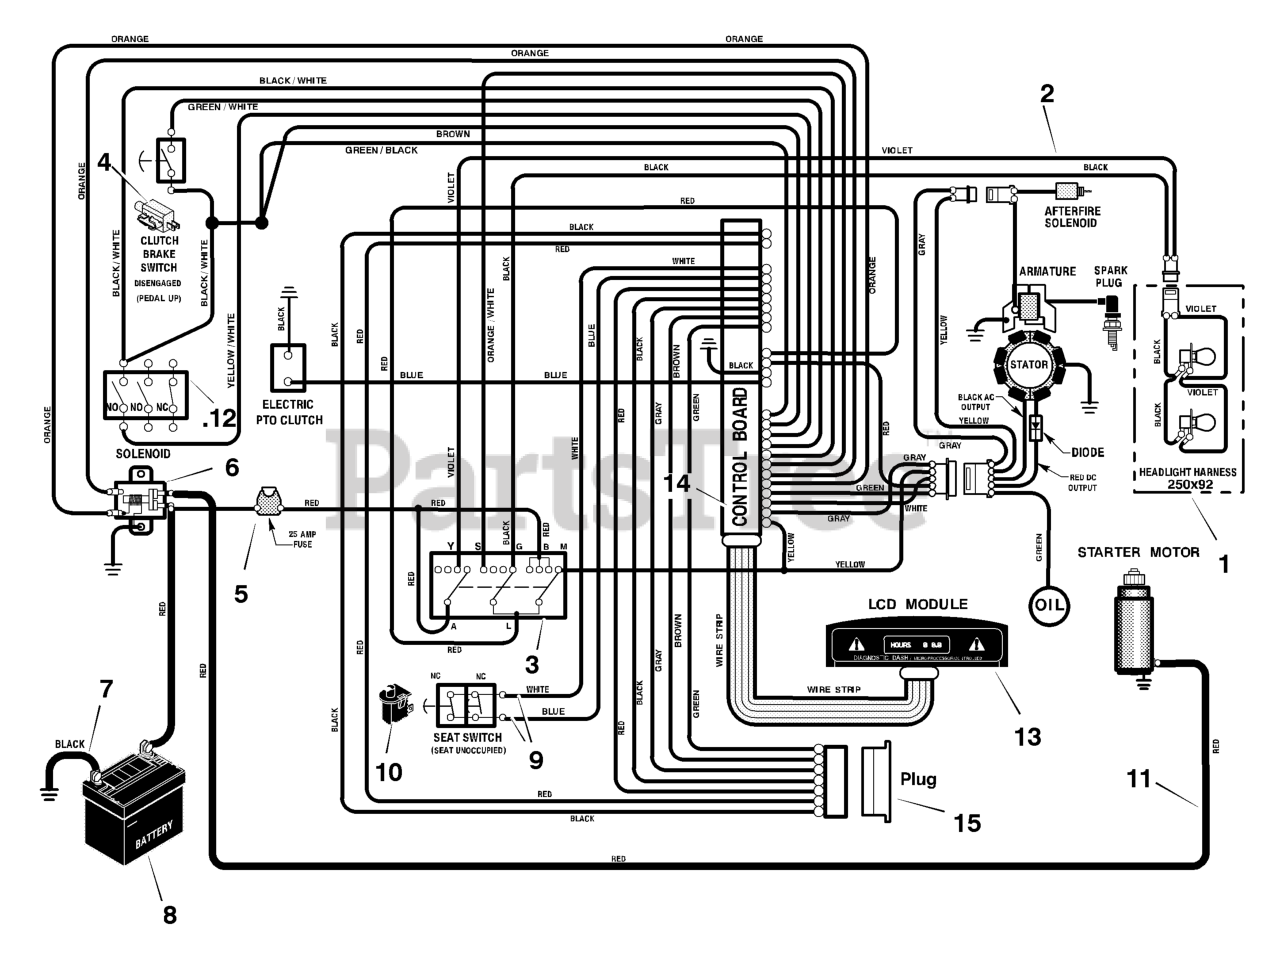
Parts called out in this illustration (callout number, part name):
1	Harness, Light Wire
2	Harness, Rear Wiring
3	Switch, Ignition
4	Switch, Clutch Limit
6	Solenoid
7	Cable, Battery Ground
8	Battery
9	Harness, Front Wiring
10	Switch, Seat Sensor
12	Switch, Electric PTO
13	Module, LCD
14	Module, Control Board
15	Plug, Electrical
